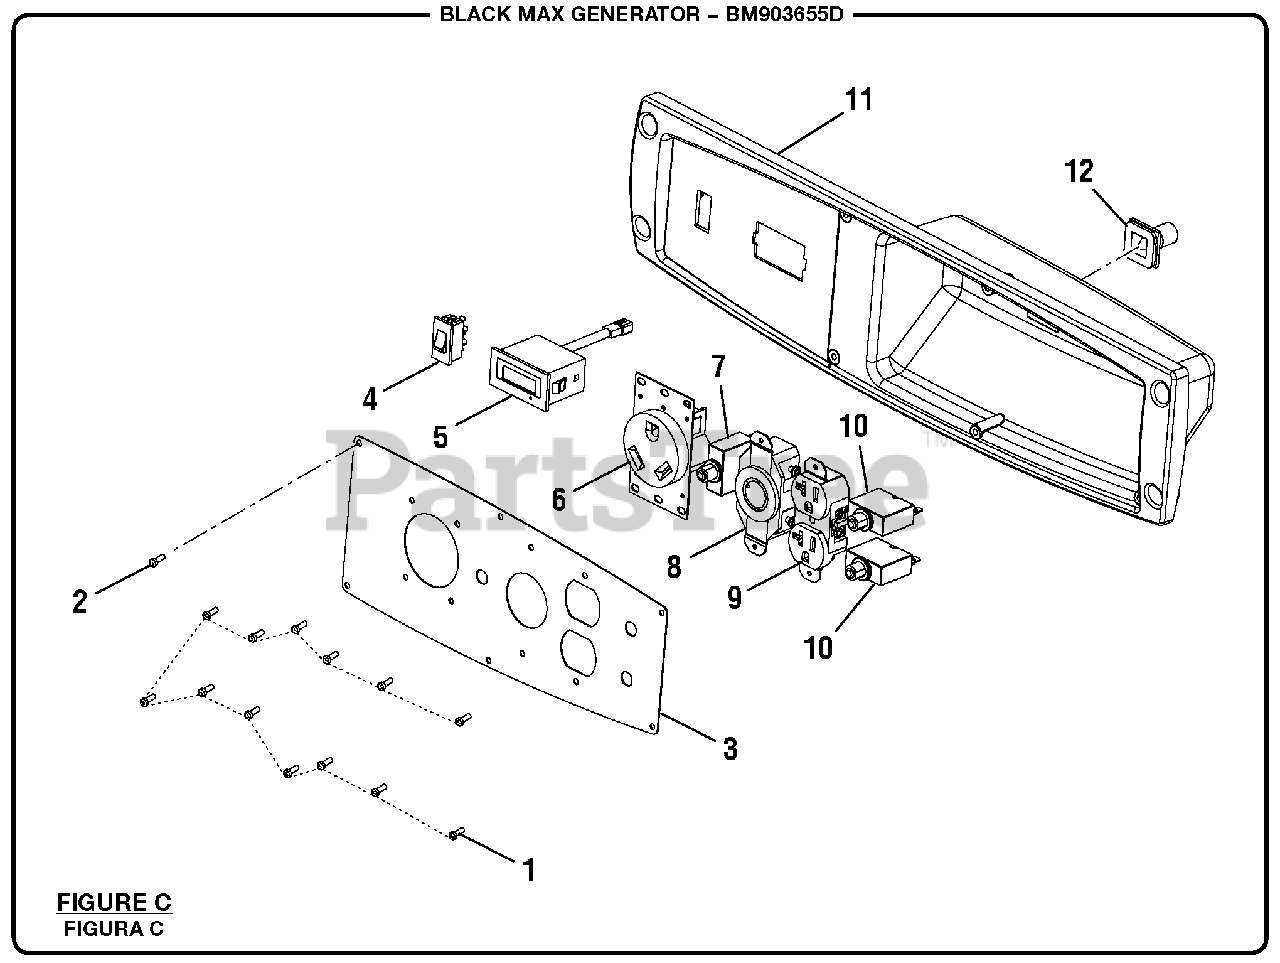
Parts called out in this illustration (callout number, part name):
1	Screw (#6-20 x 965 mm)
2	Screw (#6-20 x 20 mm)
3	Electrical Panel Assembly
5	Digital Display
6	120V/30A Recepticle (Twist Lock)
7	30A Circuit Breaker
8	120V/30A Recepticle (RV)
9	120V Duplex Receptacle
10	20A Circuit Breaker
11	Front Panel
12	Rubber Boot
